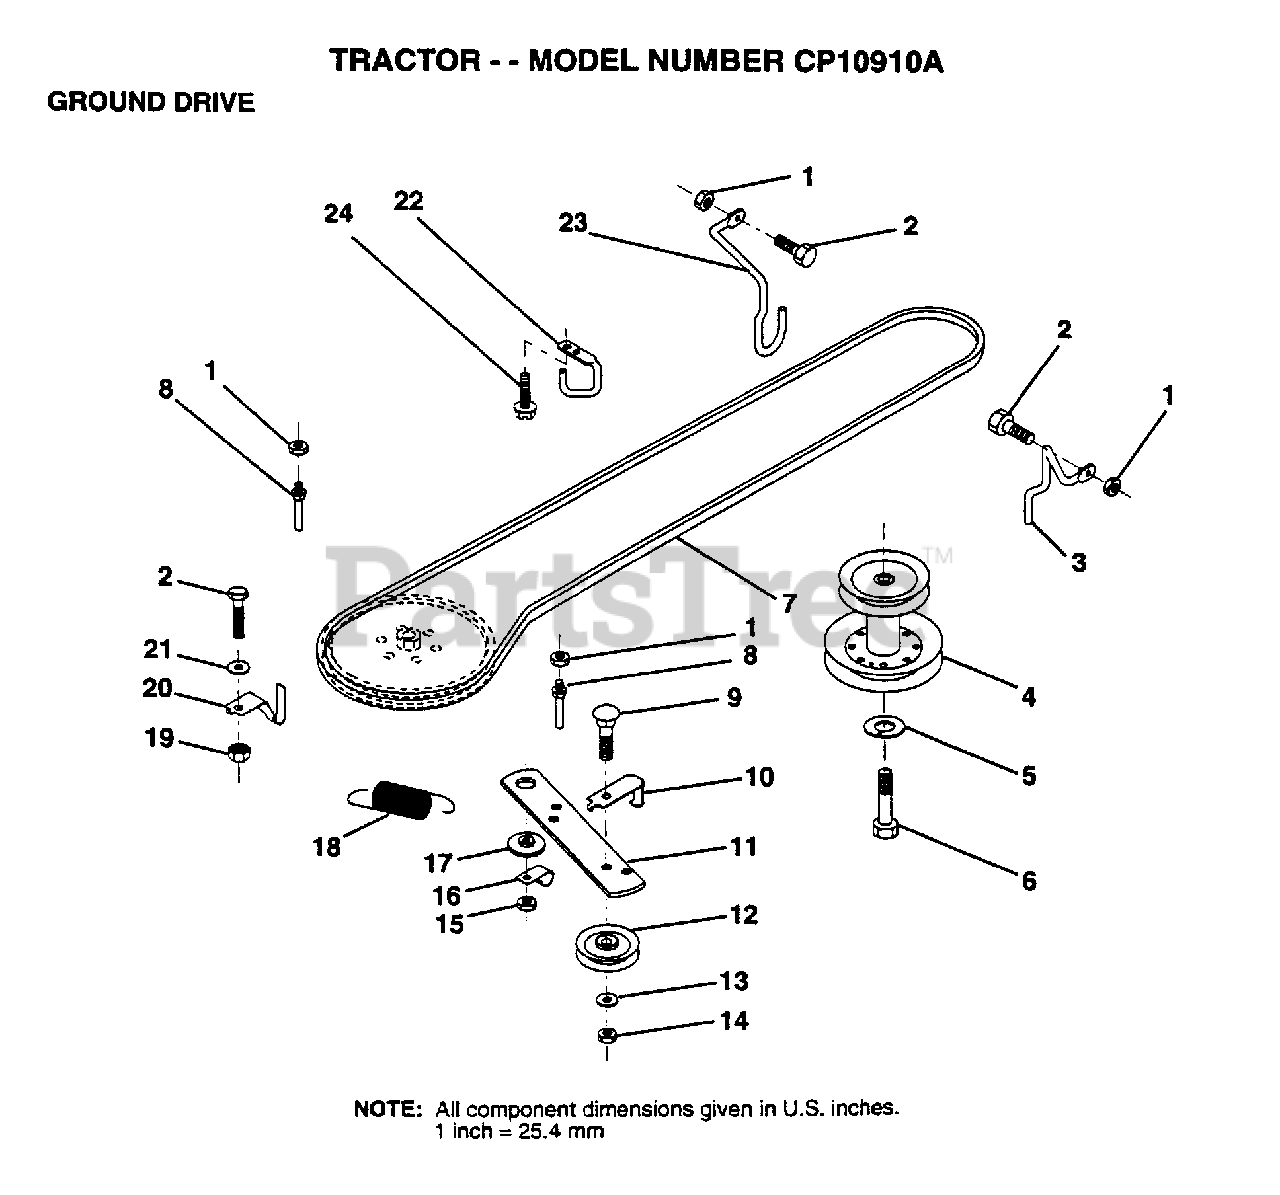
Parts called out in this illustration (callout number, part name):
2	BOLT
3	KEEPER RH
4	PULLEY.ENGINE.LR
5	LOCKWASHER
6	HEX BOLT
7	BELT
8	"KEEPER,DRIVE BELT"
9	BOLT
10	"KEEP,IDLER DR BEL"
11	ARM IDLER CLUT GD
12	PULLEY.IDLER.FLAT
13	WASHER
14	LOCKNUT
16	"CLIP,INSULATOR"
17	SPACER RETAINER
20	KEEPER.BELT.T/A
21	WASHER
22	"KEEPER,FRA DR BEL"
23	KEEPER MOWER LH
24	SCREW
